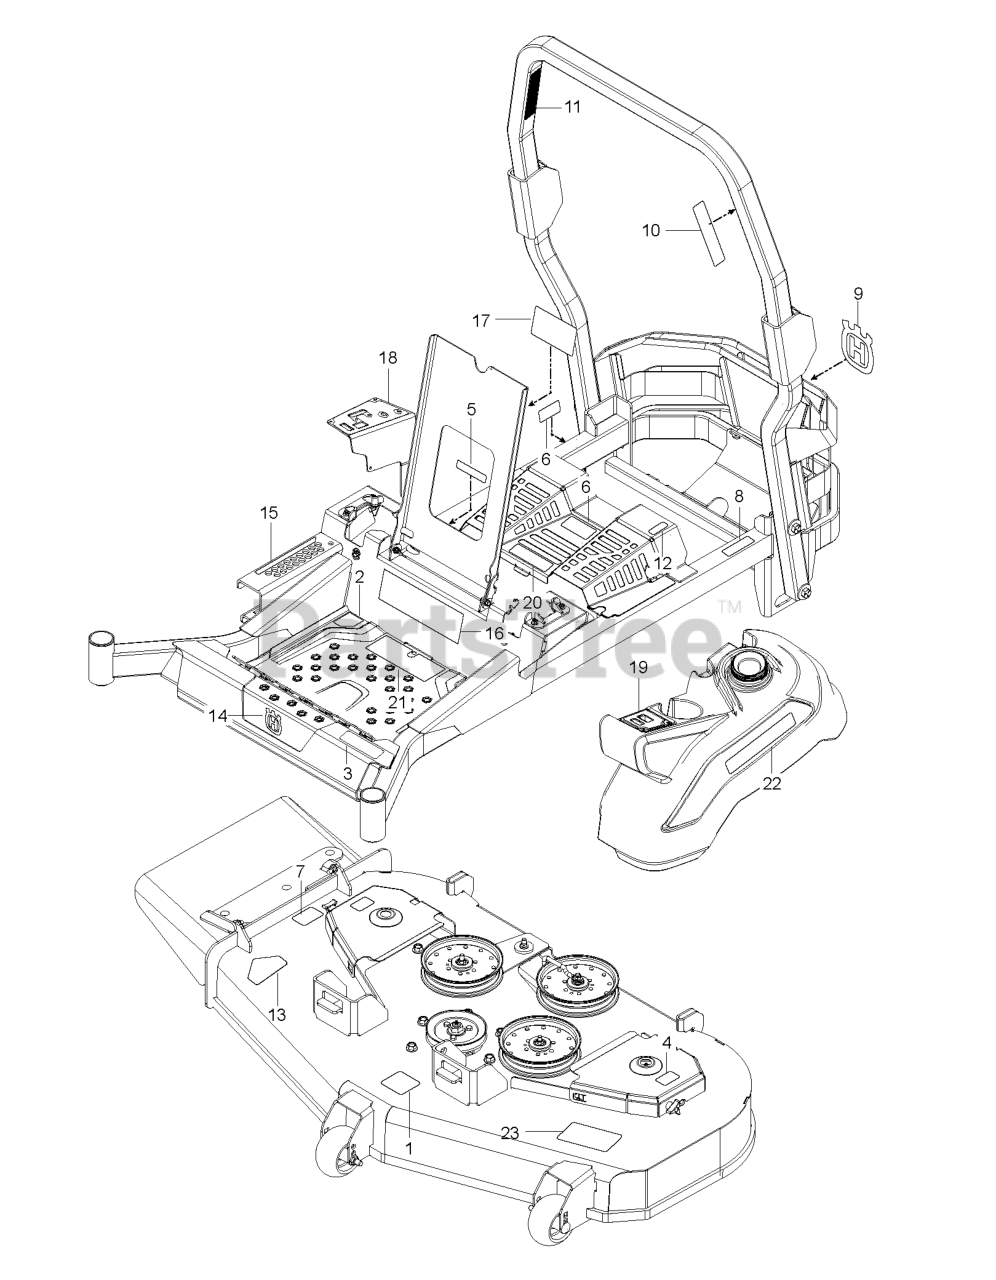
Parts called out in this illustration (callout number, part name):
1	DECAL, BELT ROUTING
2	DECAL.ZTR.SADLE.WARN.PZ500.ENG
3	DECAL.ZTR.PZ500SERIES.Z548
4	DECAL.DECK.6MIL.EURO.NOSTEP
5	EURO DECAL-BATTERY WARNIN6
6	DECAL, BELT DRIVE
7	DECAL.DECK.6MIL./DEF.SHLD.WARN
8	DECAL, WARNING SPARK ARRESTOR
9	DECAL, CROWN H, 110MM
10	DECAL, ROPS
11	DECAL, ROPS, WARNING
12	DECAL, FUSE
13	DECAL, DECK DEFLECTOR, WARNING
14	DECAL.AUGER.HUSQ.CROWN.SNOW
15	DECAL.PZ500.DECKLIFT.HUSQ
16	DECAL.ZTR.SADDLE.COMM.PZ500
17	DECAL.PZ500.MAINTANCE/SVC.2018
18	DECALZTR.CONTROLPANEL.PZ500.RH
19	DECAL.ZTR.CONTROLPANL.PZ500.LH
20	DECAL.ZTR.TRANCOVER.WARN.PZ500
21	DECAL.ZTR.SADLE.WARN.PZ500.ENG
22	DECAL.HUSQVARNA.210MM
